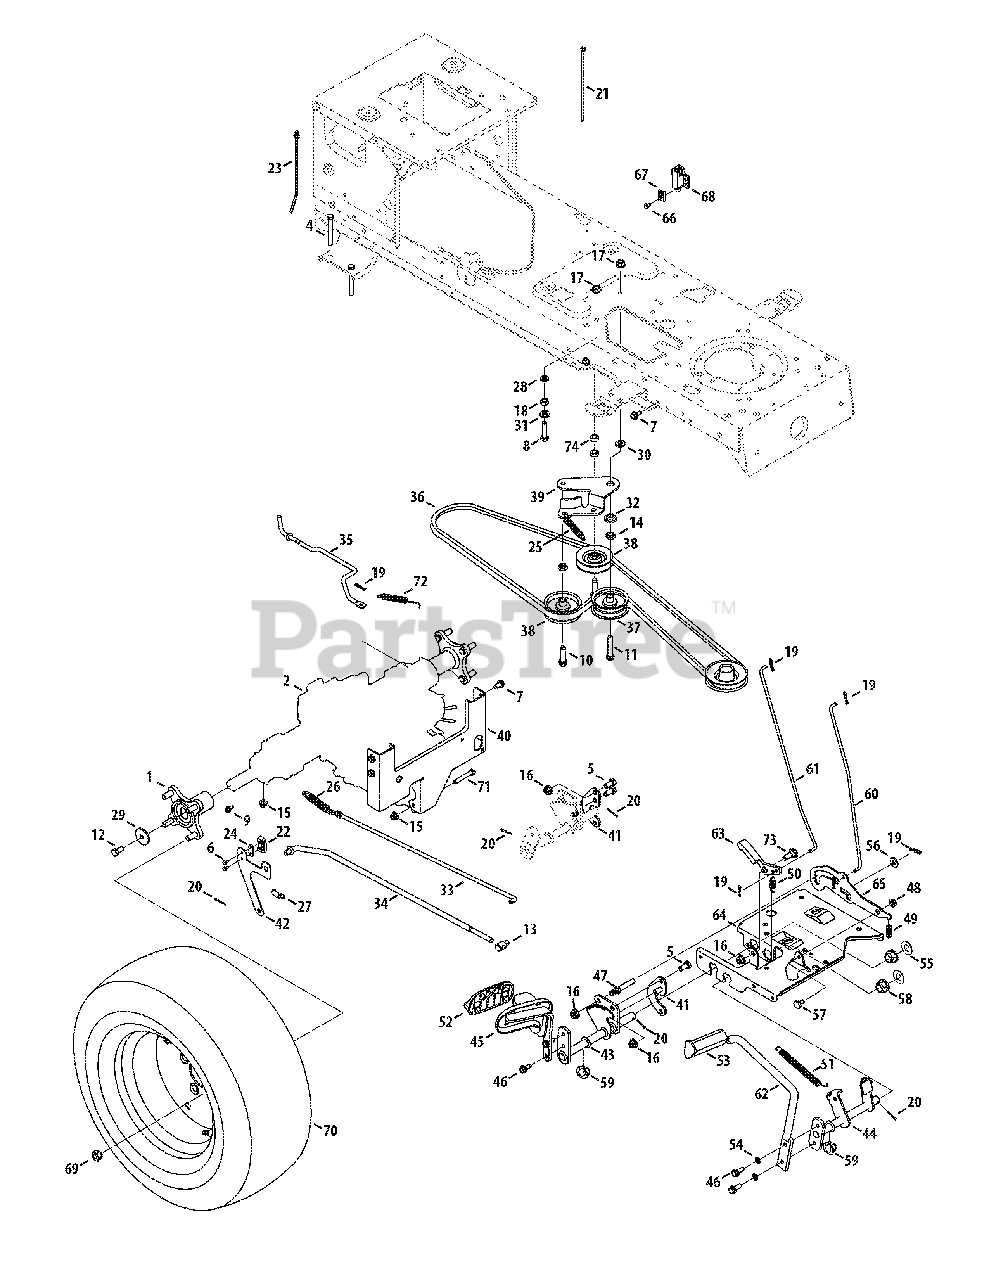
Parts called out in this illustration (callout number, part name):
1	Wheel Hub Assembly
2	Hydrostatic Transmission Assembly
4	Hex Cap Screw, 5/16-18 x 3.00
5	Hex Cap Screw, 3/8-16 x .75
6	Screw, #8-18 x .5
7	Self-tapping Screw, 5/16-18 x .750
8	Hex Cap Screw, 3/8-16 x 1.5
9	Self-tapping Screw, 1/4-20 x .50
10	Hex Cap Screw, 3/8-16 x 1.875
11	Hex Cap Screw, 3/8-16 x 2.25
12	Screw, 3/8-16 x .750
13	Ferrule, 3/8-24
14	Jam Nut, 7/16-20
15	Flange Lock Nut, 5/16-18
16	Flange Lock Nut, 3/8-16
17	Hex Nut, 3/8-16
18	Hex Nut, 3/8-16
19	Internal Cotter Pin
20	Cotter Pin
21	Cable Tie
22	Short Spring Switch
23	Push-mount Cable Tie
24	Insulator Nut Plate
25	Extension Spring, .770 x 3.72 Lg.
26	Extension Spring, .59 x 4.0
27	Extension Spring, 3/8 x 1.44
28	Lock Washer, 3/8
29	Flat Washer, .390 x 1.500 x.134
30	Flat Washer, .385 x 1.00 x.135
31	Flat Washer, .406 x .875 x .059
32	Shoulder Spacer, .38
33	Hydrostatic Brake Rod
34	Hydrostatic Control Rod
35	Hydrostatic Bypass Rod
36	Drive Belt
37	Flat Idler Pulley, 2.75
38	V-idler Pulley, 3.06
42	Switch Actuator Bracket
43	Drive Control Assembly
44	Brake Control Assembly
45	Hydro Pedal Assembly
46	Self-tapping Screw, 5/16-18 x.75
47	Pin, 3/8-16 x 2.43
48	Flange Lock Nut, 5/16-18
49	Compression Spring, .40 OD x 1.17
50	Extension Spring, .50 OD x 1.41
51	Extension Spring, . 50 OD x 6.37
52	Drive Pedal Pad
53	Brake Pedal Pad
54	Lock Washer, 5/16
55	Flat Washer, .64 x 1.24 x.06
56	Flat Washer, .385 x.870 x.092
57	Shoulder Screw, .437 x 1.62
58	Hex Flange Bearing
59	Split Hex Flange Bearing
60	Brake Lock Control Rod
61	Cruise Control Rod
62	Brake Pedal
63	Cruise Latch
64	Steering Support Bracket
65	Drive Lockout Bracket
66	AB Screw, #10-16 x.500
67	Switch Plate
68	Switch
69	Lug Nut, 3/4-16
70	Wheel Assembly, 23 x 10.5 x 12
70	Rim Only 12.0 x 7.0
70	Air Valve
70	Tire Only 23 x 10.5 x 12 Sq. Shldr.
71	Hex Cap Screw, 5/16-18 x 2.00
72	Extension Spring, .50 OD x 5.00
73	Shoulder Bolt, .500 x .270 x 3/8-16
74	Spacer, .380 ID x .625 OD x .265
